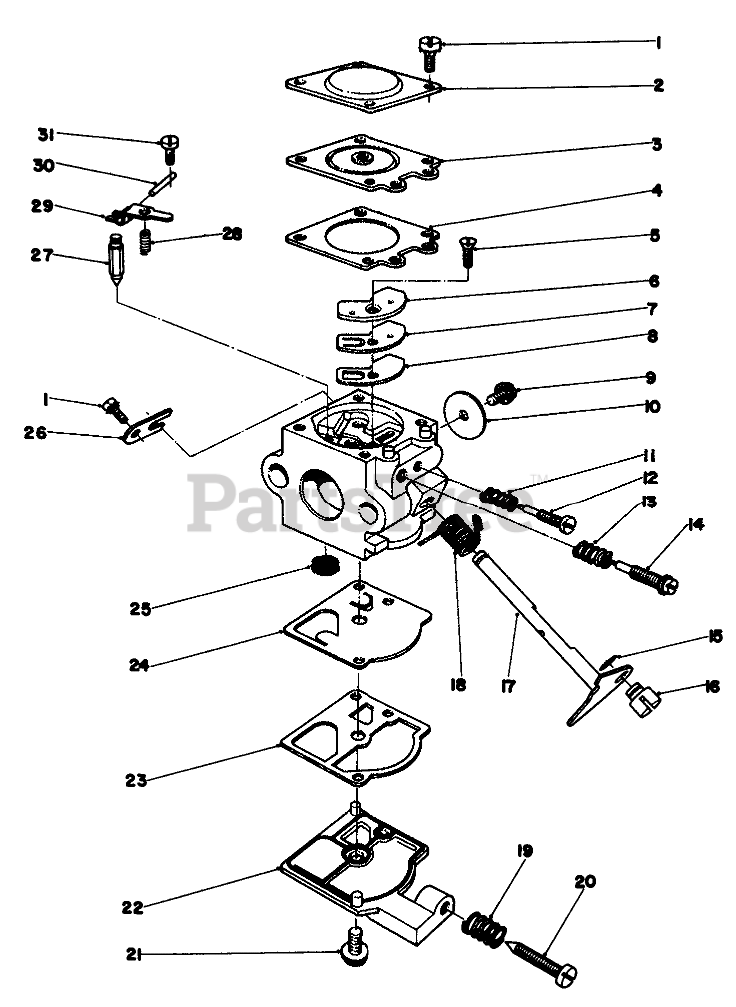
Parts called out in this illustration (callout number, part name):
1	Screw
2	Cover, Diaphragm
3	METERING DIAPHRAGM
4	Gasket, Diaphragm
5	Screw-Circuit Plate
6	Plate, Circuit
7	Diaphragm Circuit Plate
8	Gasket-Circuit Plate
9	Screw
10	Valve, Throttle
11	Spring, Needle
12	Idle Needle
13	Spring, HS Needle
14	Needle, HS
16	Swivel
17	THROTTLE SHAFT ASM
18	Spring-Throttle Lever
19	Spring, Idle Screw
20	Screw, Idle Adjust
21	Screw
22	Cover, Fuel Pump
23	PUMP GASKET
24	Diaphragm Fuel Pump
25	Screen Inlet
26	Clip Throttle Shaft
27	INLET NEEDLE VALVE
28	Spring, Lever
29	Lever Metering
30	Metering Lever Pin
31	Screw-Metering Pin
